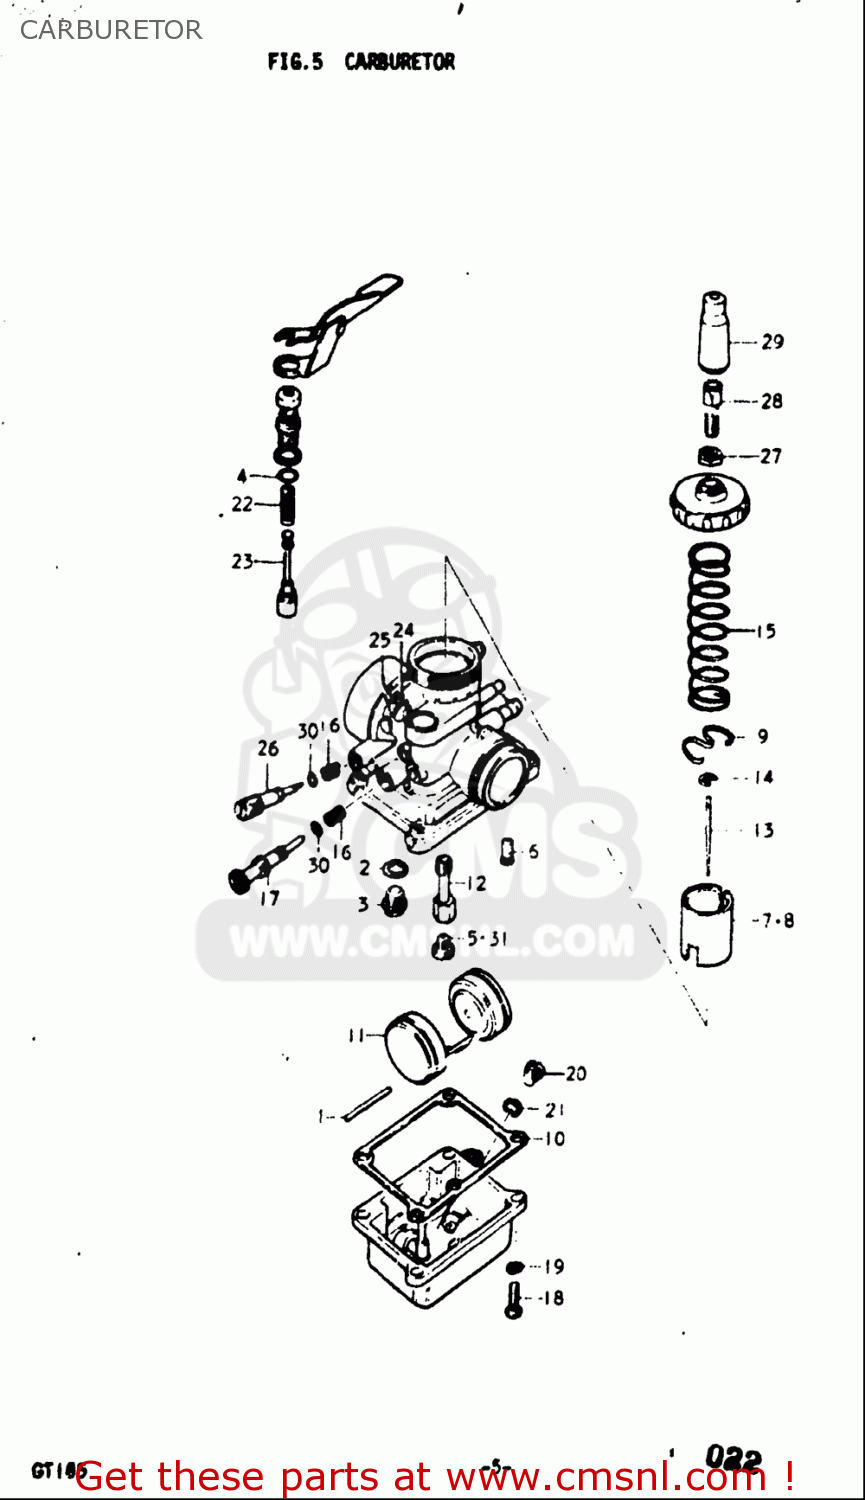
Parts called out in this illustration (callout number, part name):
1	PIN,FLOAT
2	GASKET,NEEDLE VALVE (NAS)
3	VALVE ASSY,NEEDLE
4	O RING(D:1.5,ID:8.5)
5	JET,MAIN(72.5)
6	JET,PILOT 20
9	STOPPER,NEEDLE CLIP
10	GASKET,FLOAT CAHMBER (NAS)
11	FLOAT
14	CLIP
15	SPRING,THROTTLE VALVE
16	SPRING
17	SCREW,THROTTLE STOP
18	SCREW 4X16
19	WASHER,LOCK
20	PLUG
21	GASKET,DRAIN,PLUG (NAS)
22	SPRING
23	PLUNGER,STARTER
24	GASKET,THRO VALVE INSPECTION (NAS)
25	BOLT
26	SCREW,PILOT AIR
27	NUT
28	ADJUSTER,CABLE
29	CAP,CABLE ADJUSTER
30	O RING
31	JET,MAIN
